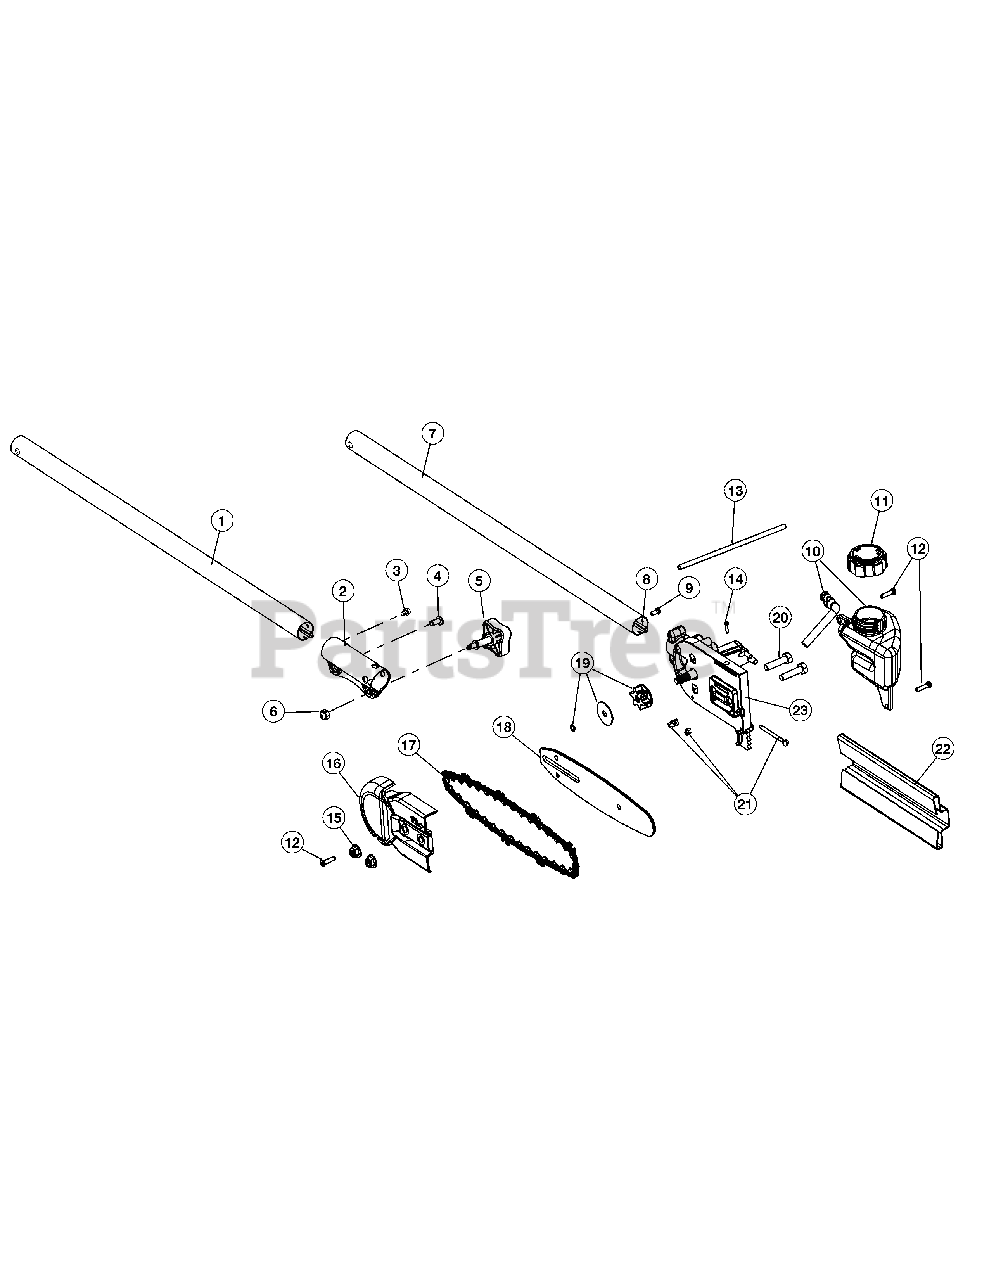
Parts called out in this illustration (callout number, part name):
1	Extension Boom
2	Split Boom Coupler
5	Adjustment Knob
6	Knob Retaining Nut
7	Drive Shaft Housing
8	Flexible Drive Shaft
9	Screw
10	Oil Tank Assembly
11	Fuel Cap Assembly
12	Screw
14	Screw
15	Nut
16	Chain Guard
17	Chain Guard
19	Sprocket Assembly
20	Bolt
21	Chain Tension Hardware Assembly
22	Chain Cover
23	Gearbox Assembly
